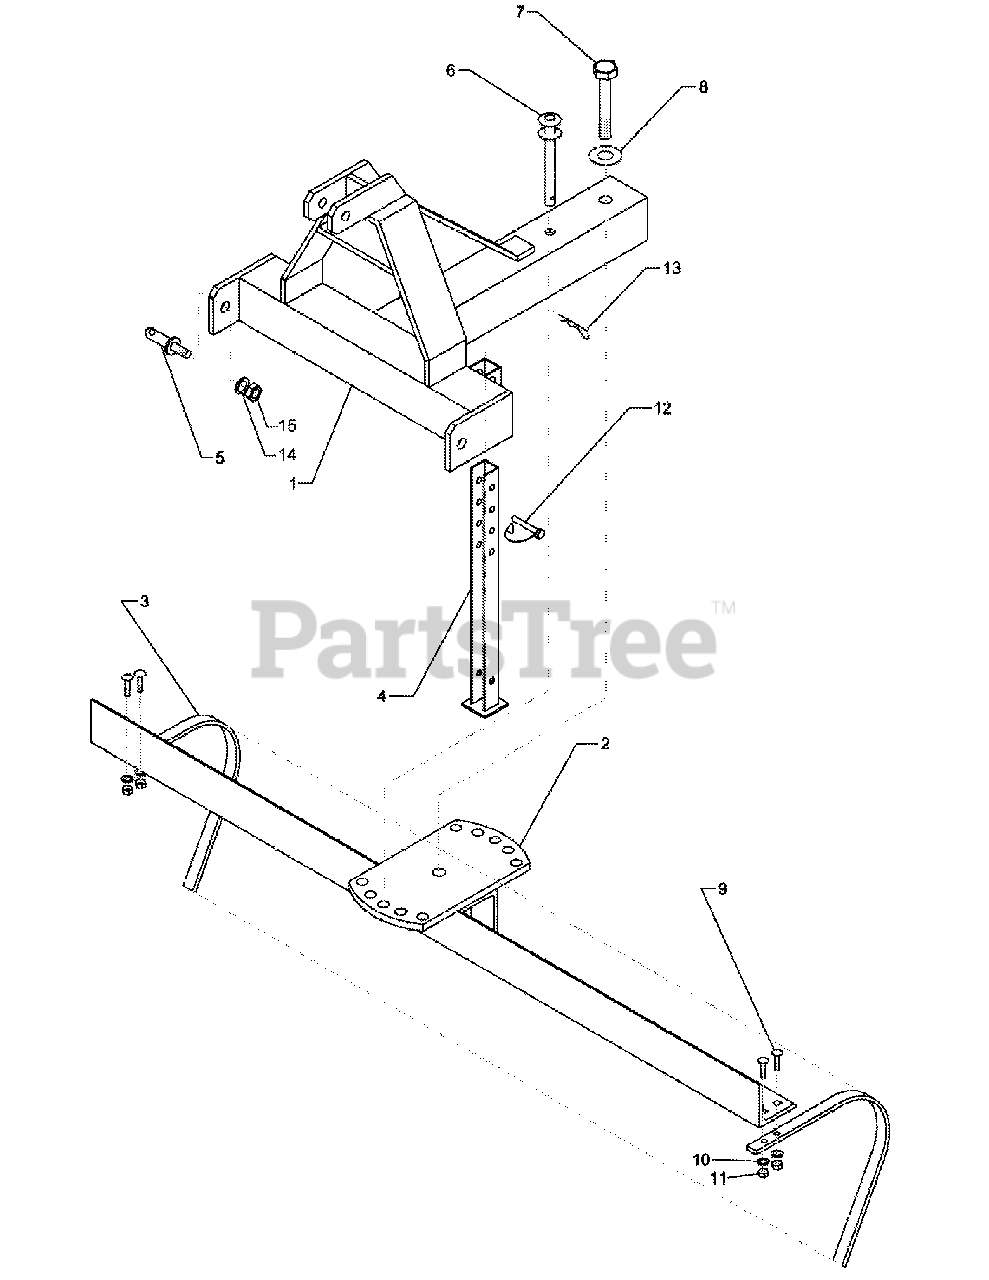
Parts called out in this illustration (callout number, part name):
1	A-Frame (LR72 & LR84)
2	Welded swivel (LR72)
2	Welded swivel ( LR84)
3	Rake tine with 2 holes (LR72 & LR84)
4	Foot stand
5	Hitch pin 7/8"
6	Swivel pin 3/4"x6" (LR72 & LR84)
7	Hex bolt 1"x6" (LR72 & LR84)
8	Flat washer 1" (LR72 & LR84)
9	Carriage bolt 3/8"-16x1.25" (LR72 & LR84)
10	Lock washer 3/8"
11	Hex nut 3/8"
12	Lynch pin
13	R clip Ø4
14	Lock washer 7/8"
15	Hex nut 7/8"
